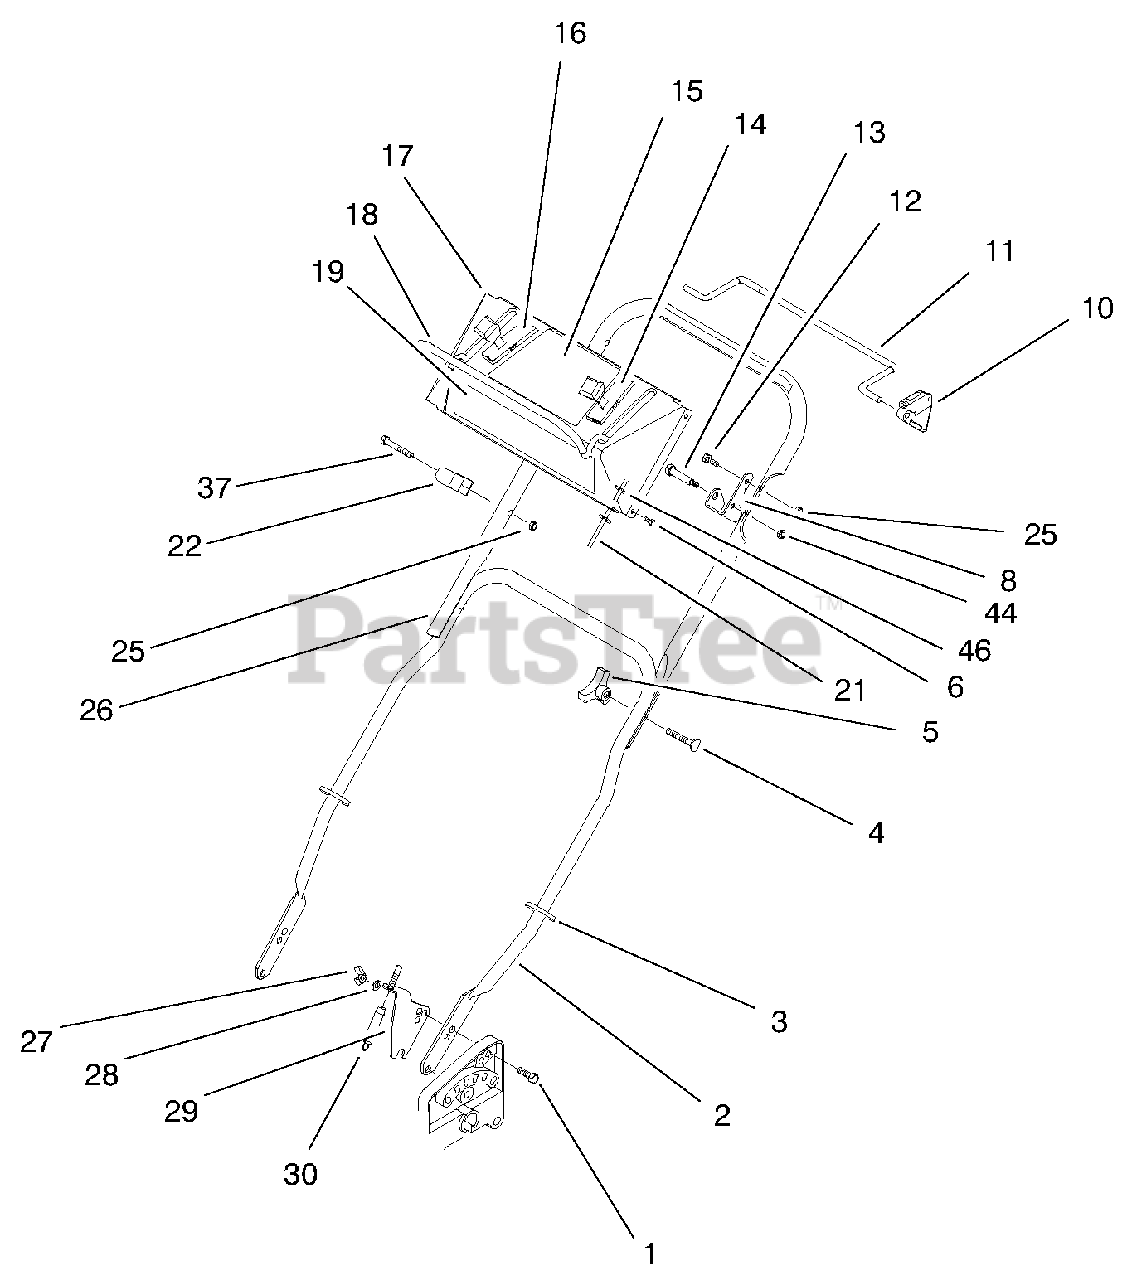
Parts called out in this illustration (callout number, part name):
1	Bolt-CARR.
2	Handle Section-Lower
3	Tie Strap
4	Screw-Handle
5	Knob
6	Screw-Phil
8	Bail Stop Bracket
10	Stop-Pivot
11	Sp Control Bail
12	Screw-HH
14	Throttle-Control
15	Decal-Control Panel
16	Control-Speed
17	Panel-Control (Incl. Ref. #15, & 19)
18	Engine Control Bail
19	Decal-Front Console
21	Cable-Brake
22	Guide-Rope
25	Nut-Lock
26	Handle-Upper
28	Washer-Lock
29	Bracket-Traction Cable
30	ASM-Cable
37	Bolt-Hex
44	Nut-Lock
46	Washer-Flat
